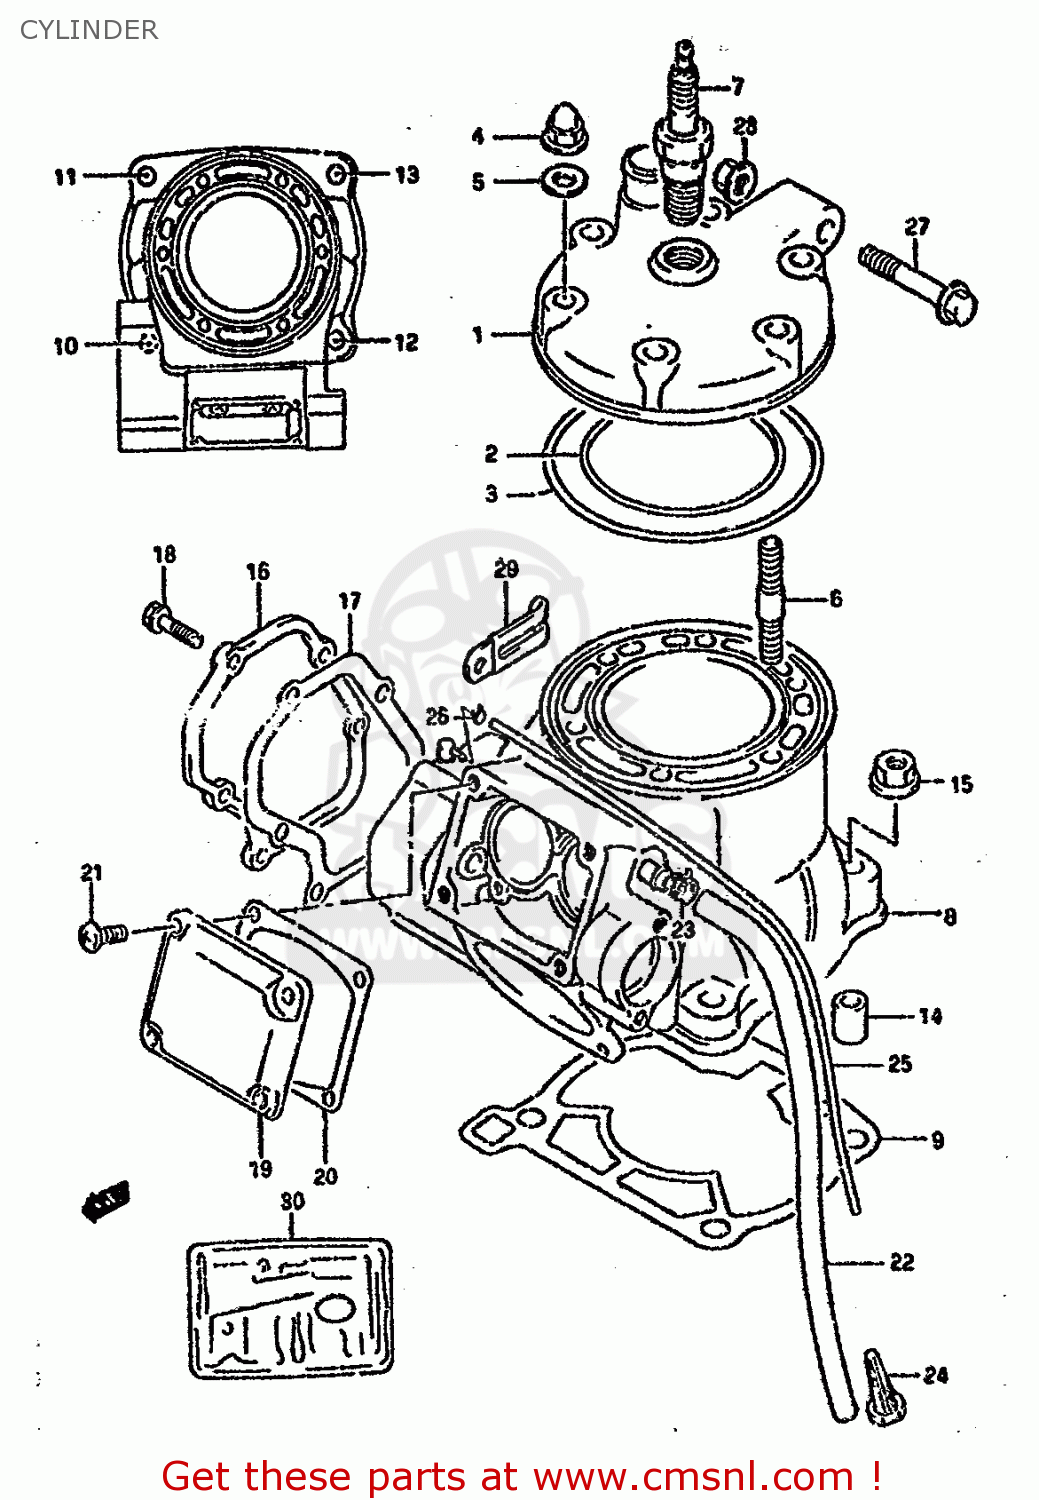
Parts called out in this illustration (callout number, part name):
1	HEAD,CYLINDER
2	O RING,CYLINDER HEAD NO.1
3	O RING,CYLINDER HEAD NO.2
4	NUT
5	GASKET(8.5X17X2.3) (NAS)
6	BOLT,STUD
7	PLUG,SPARK(R4118S-8)
8	CYLINDER SET
9	GASKET,CYLINDER (NAS)
10	STUD 10X30
11	STUD BOLT
12	STUD BOLT (L:40)
13	BOLT,STUD
14	PIN
15	NUT
16	COVER,CYLINDER NO.1
17	GASKET,CYL COVER (NAS)
18	BOLT
19	COVER,CYLINDER NO.2
20	GASKET,CYLINDER COVER (NAS)
21	BOLT
22	HOSE
23	CLIP
24	FILTER,EXH VALVE BREATHER HOSE
25	HOSE(5X8.2X600)
26	CLIP
27	BOLT(8X45)
28	NUT
29	CLAMP
30	GASKET SET (NAS)
